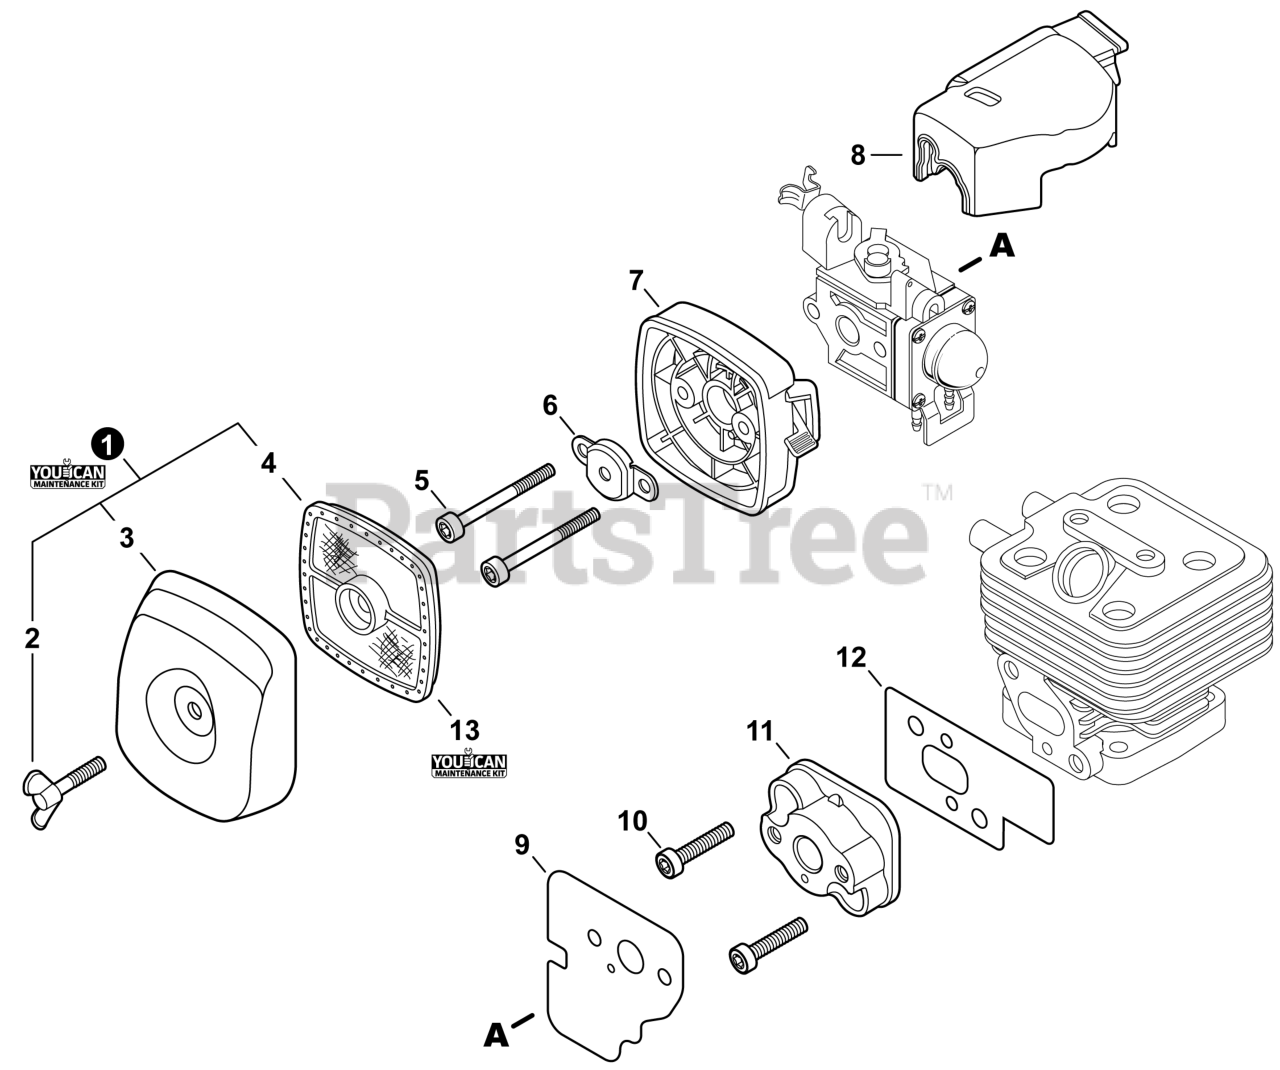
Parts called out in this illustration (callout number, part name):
1	FILTER KIT, AIR - YOUCANT
2	BOLT, WING 5×20
3	COVER, AIR FILTER - BLACK
4	FILTER, AIR - DOUBLE LAYER
5	BOLT, TORX 5×65
6	PLATE, PREVENT
7	CASE, AIR FILTER
8	COVER, DUST
9	GASKET, INTAKE
10	BOLT, TORX 5×25
11	INSULATOR, INTAKE
12	GASKET, INTAKE
13	TUNE-UP KIT - YOUCANT
